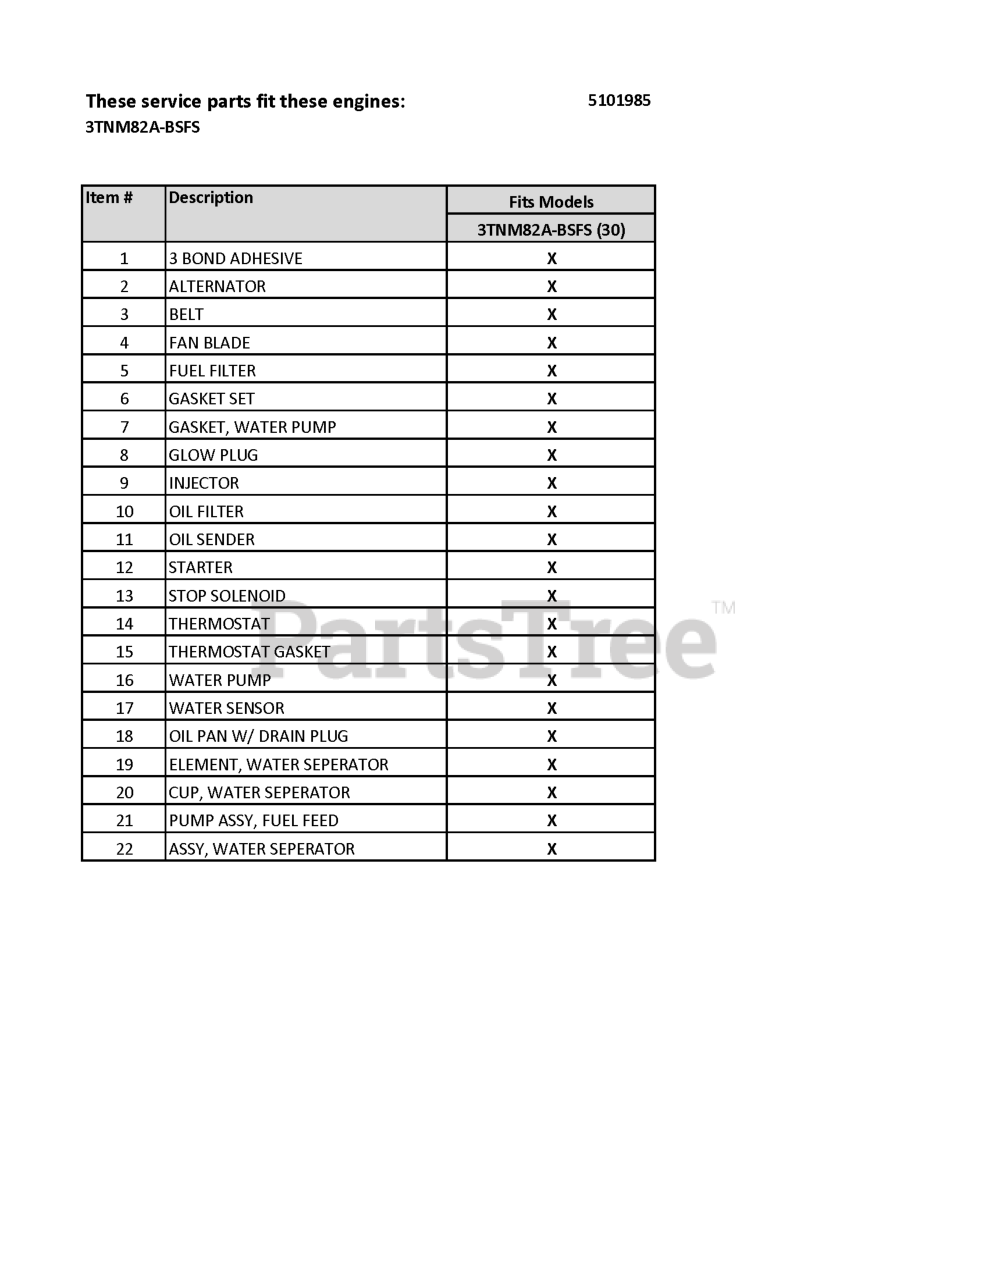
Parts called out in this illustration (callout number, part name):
1	3 BOND ADHESIVE
2	ALTERNATOR
4	FAN BLADE
5	FUEL FILTER
6	GASKET SET
7	GASKET, WATER PUMP
8	GLOW PLUG
10	OIL FILTER
11	OIL SENDER
13	STOP SOLENOID
14	THERMOSTAT
15	THERMOSTAT GASKET
16	WATER PUMP
17	TEMPERATURE SENDER
18	OIL PAN W/ DRAIN PLUG
19	ELEMENT, WATER SEPARATOR
20	CUP, WATER SEPARATOR
21	PUMP ASSY, FUEL FEED
22	ASSY, WATER SEPARATOR
